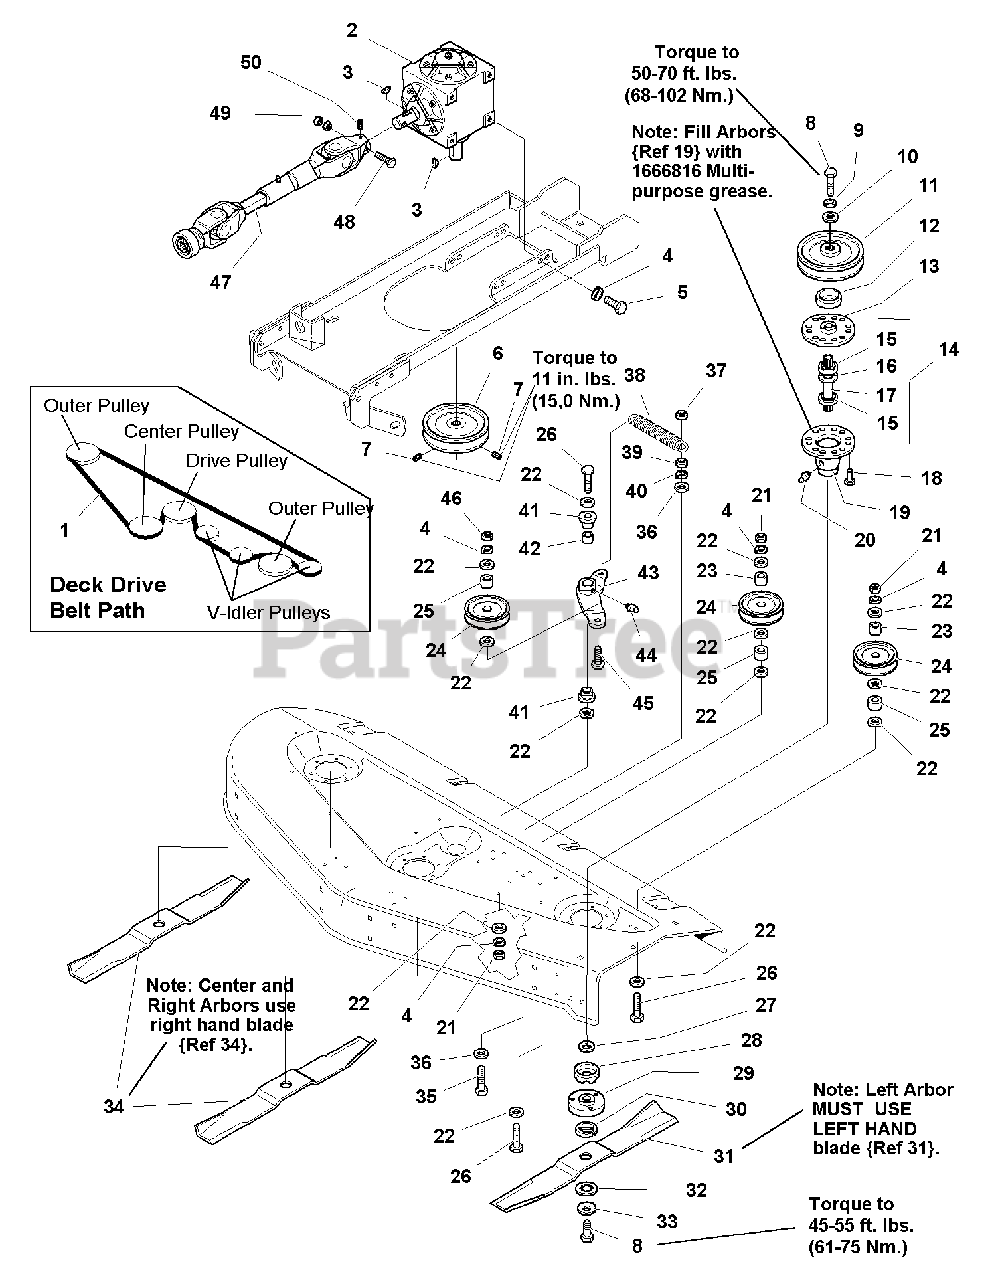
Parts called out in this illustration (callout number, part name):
1	BELT, Deck, Double V
2	GEAR BOX (See Gear Box Service Parts )
4	LOCKWASHER, 3/8
5	CAPSCREW, Hex Head, 3/8-16 x 3/4
6	PULLEY ASSEMBLY
7	SETSCREW, 5/16-18 x 1/2
8	CAPSCREW, Hex Head, 7/16-14 x 1-1/4, G8
9	LOCKWASHER, 7/16
10	WASHER, 7/16
11	PULLEY ASSEMBLY
12	SHIELD, Bearing Upper, Arbor
13	ARBOR HOUSING, Top
14	ARBOR SHAFT & BEARING ASSEMBLY (Includes Ref. Nos. 15, 16 & 17)
16	GASKET, Foam
17	ARBOR SHAFT
18	CAPSCREW, Hex Head, Taptite, 5/16-18 x 3/4
19	HOUSING ASSEMBLY, Bottom (Includes Ref. No. 20)
20	FITTING, Lube
21	NUT, Hex, 3/8-16
22	WASHER, Plain, 3/8
23	SPACER (In Pulley)
24	PULLEY, Idler
26	CAPSCREW, Hex Head, 3/8-16 x 2
27	WASHER, Shim
28	SHIELD, Grass
29	ADAPTER, Blade
30	RING, Self Locking
31	BLADE, Left Hand (Left Arbor Only)
32	WASHER, Spline
33	WASHER, Spring
34	BLADE, Right Hand (Right and Center Arbors)
35	CAPSCREW, Hex, 5/16-18 x 1 3/4
36	WASHER, Plain 5/16
37	NUT, Hex Lock, 5/16-18
38	SPRING, Extension
39	NUT, Hex, 5/16-18
40	LOCKWASHER, 5/16
43	IDLER ARM ASSEMBLY
44	FITTING, Lube
45	CARRIAGE BOLT, 3/8-16 x 1 1/4
46	NUT, Hex Lock, 3/8-16
47	DRIVE SHAFT, Complete (See Drive Shaft Service Parts )
48	CAPSCREW, Hex Head, 1/4-20 x 2 1/2
49	NUT, Hex Lock, 1/4-20
50	SETSCREW, 5/16-18 x 1/2
